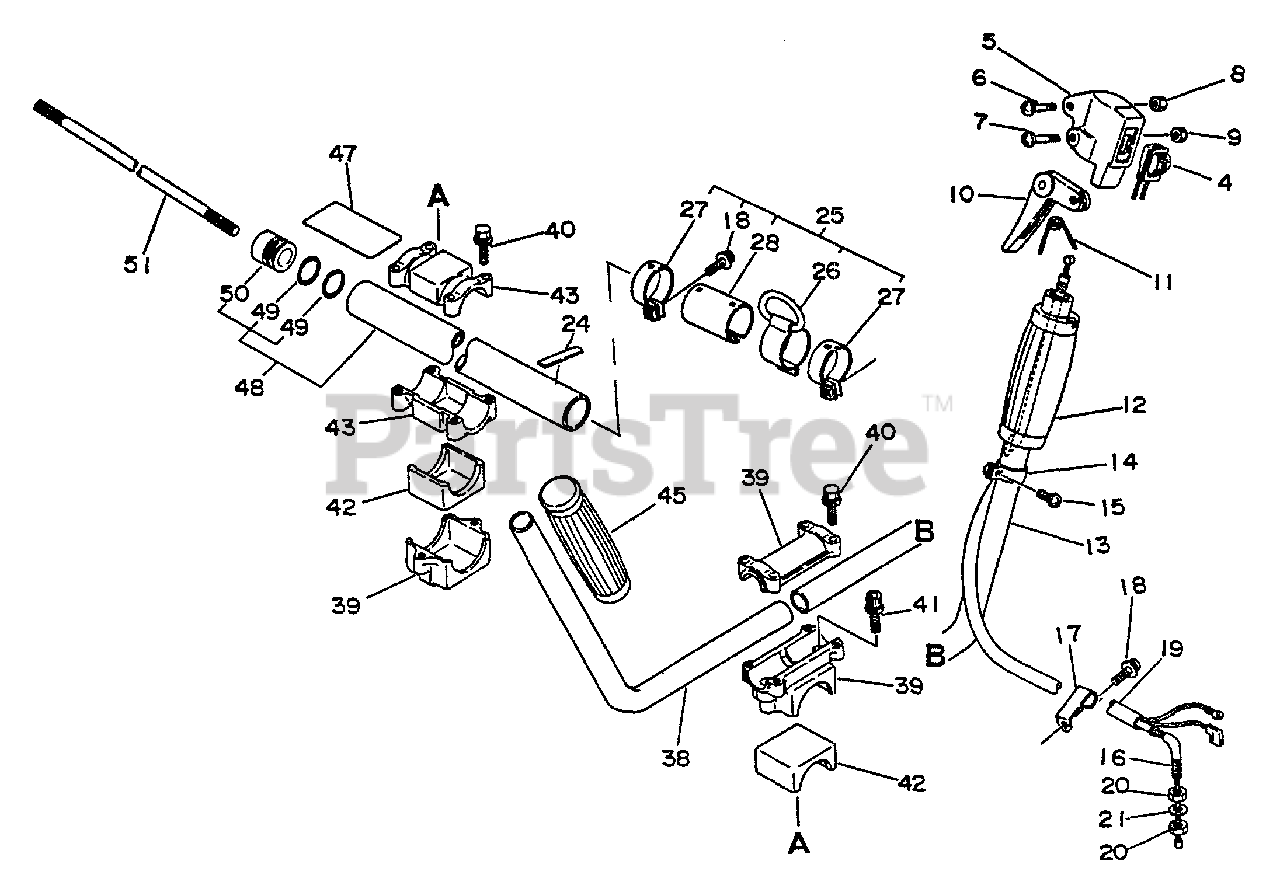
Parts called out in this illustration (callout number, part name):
4	IGNITION SWITCH ASSY
5	BRACKET, THROTTLE
6	SCREW - 5X30
7	SCREW - 5X25
8	LOCKNUT - 5
10	TRIGGER, THROTTLE
11	SPRING, TRIGGER
12	GRIP, HANDLE
15	SCREW - 5X10
16	CABLE, THROTTLE
18	SCREW - 5X14
19	TUBE
21	WASHER - 6
24	LABEL - ALIGNMENT
25	HANGER KIT
25	HOOK
26	HOOK
27	COLLAR
28	COLLAR
38	HANDLE, FRONT - LEFT
39	BRACKET ASSY
40	BOLT - 5X25
41	SCREW - 5X25
42	CUSHION
43	BRACKET KIT
45	GRIP, HANDLE - LEFT
47	LABEL - CAUTION
48	MAIN PIPE ASSY
50	STOPPER
51	DRIVESHAFT - SOLID
